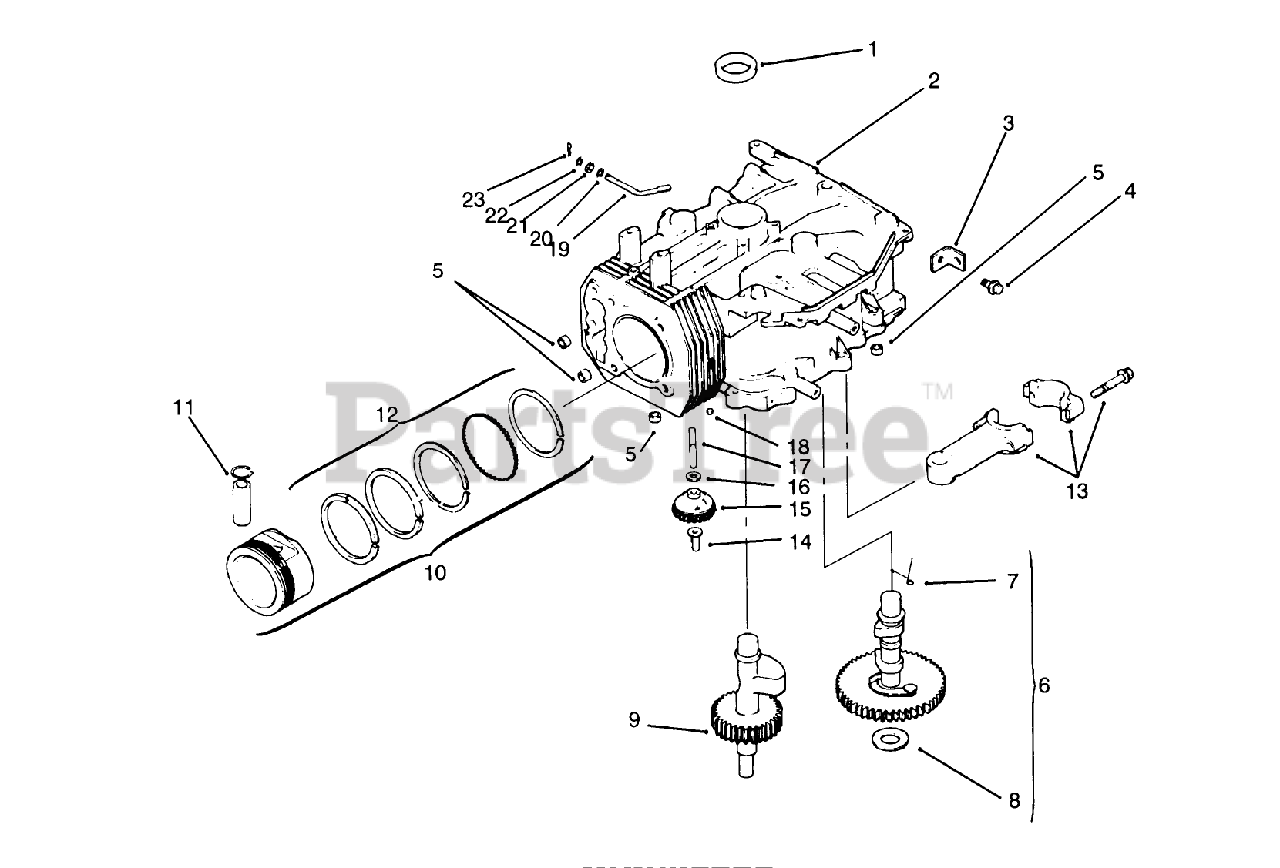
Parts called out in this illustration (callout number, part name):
1	Seal-Crankshaft (Only On: 72042, 72043, 72062, 72063)
3	Strap-Lifting (Only On: 72042,72043,72062,72063)
4	Screw M8x1.25x22 (Only On: 72042, 72043, 72062, 72063)
5	Pin-Dowel
6	Kit-Camshaft INC 7-8 (Only On: 72042, 72063, 72062, 72043)
7	Spring-Actuating (Only On: 72042,72043,72062,72063)
8	Shim-Camshaft
9	Shaft-Balance (Only On: 72042, 72043, 72062, 72063)
10	Piston ASM STD INC 11-12 (Only On: 72042, 72063, 72062, 72043)
10	Piston ASM .25 INCL 11-12 (Only On: 72042,72043,72062, 72063)
10	Piston ASM .50 INCL 11-12 (Only On: 72042, 72043, 72062, 72063)
11	Retainer-Piston Pin (Only On: 72042, 72043,72062,72063)
12	Ring Set STD (Only On: 72042,72043,72062,72063)
12	Ring Set .25 (Only On: 72042,72043,72062,72063)
12	Ring Set .50 (Only On: 72042,72043,72062,72063)
13	Connecting Rod STD (Only On: 72042, 72063, 72062, 72043)
13	Connecting Rod .25 (Only On: 72042, 72063, 72062, 72043)
14	Pin-Governor
15	Gear-Governor ASM (Only On: 72042, 72063, 72062, 72043)
17	Shaft-Govenor Gear
19	Shaft-Governor Cross (Only On: 72042, 72063, 72062, 72043)
20	Washer-Governor Shaft (Only On: 72042, 72063, 72062, 72043)
21	Seal
22	Washer
23	Pin-Hitch
